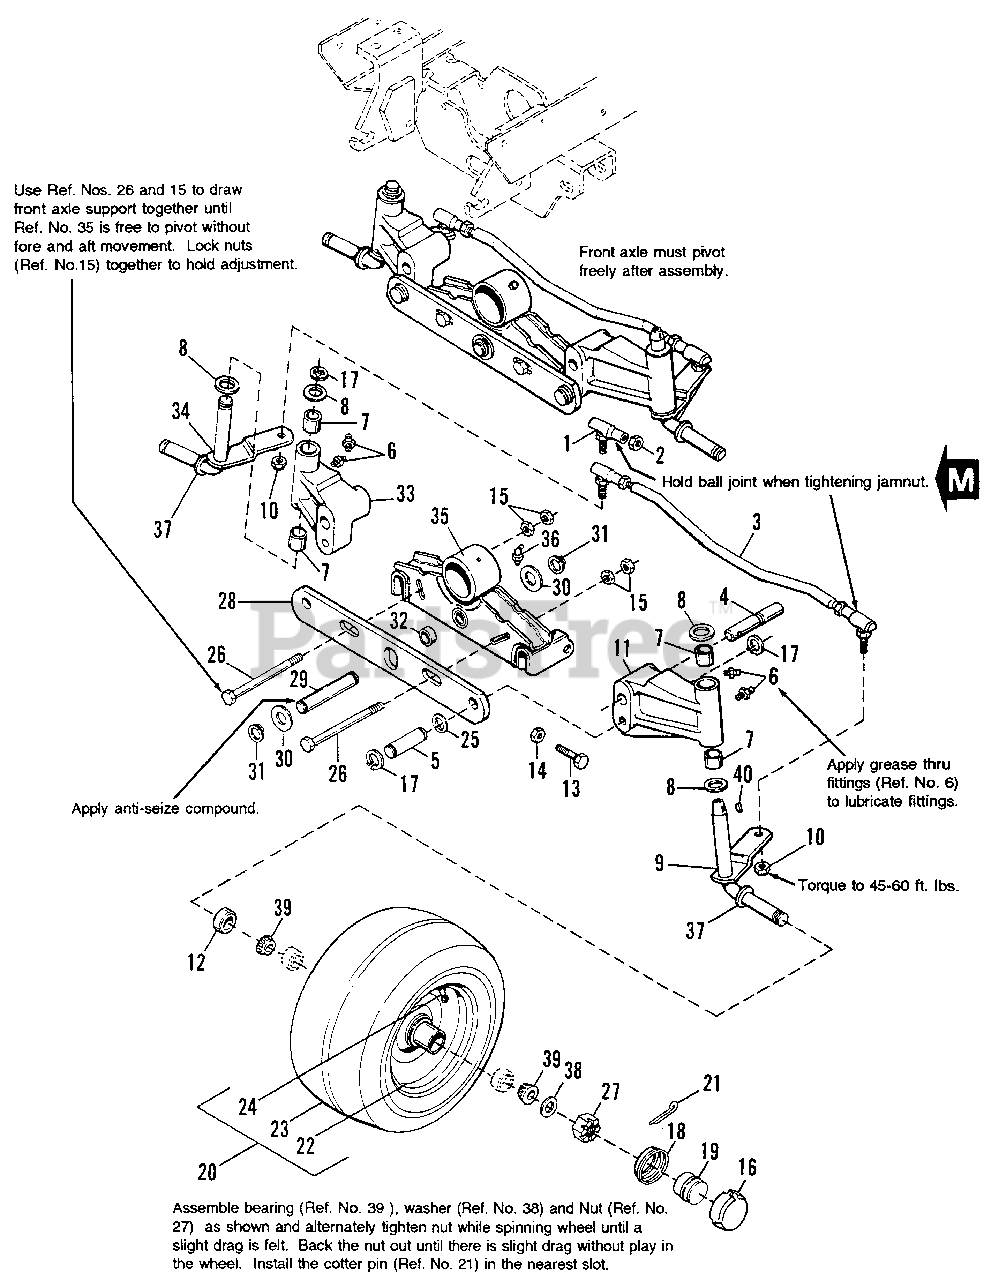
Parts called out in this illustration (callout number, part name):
1	BALL JOINT ASSY.
2	NUT, Hex, Jam, 1/2-20
3	TIE ROD ASSY. (Incl. Ref. No. 1 & 2)
4	PIN, Axle Pivot
5	PIN, Axle Pivot
6	FITTING, Lube, 1/4-28
7	BUSHING, Spindle
8	WASHER, 1-1/32 x 1-5/8 x 1/16
9	SPINDLE ASSY. L.H., (Includes Ref. No. 37)
10	NUT, Hex, Centerlock, 1/2-20
11	AXLE PIVOT ASSY., L.H. (Incl. Qty 2 of Ref. Nos. 6 & 7)
13	CAPSCREW, Hex Hd., 5/16-18 x 1-3/4, Gr. 5
14	NUT, Hex, Centerlock, 5/16-18
15	Nut, Hex, 3/8-16
16	CAP, Hub, Cover
17	RING, Retainer
18	RETAINER, Hub Cap
20	FRONT WHEEL & TIRE ASSY., 16 x 6.50-8 (Incl. Ref. Nos. 22. 23 & 24)
21	PIN, Cotter, 1/8 x 1 3/4
22	WHEEL ASSY., w/Bearings (Incl. Ref. No. 39)
23	TIRE, 16 x 6.50-8
24	VALVE STEM & CAP
25	WASHER, 1 1/32 x 1 3/4 x 7 Ga.
26	CAPSCREW, Hex Hd., 3/8-16 x 4
27	NUT, Hex, Slotted Hd., 3/4-16
30	WASHER, 3/4 I.D.
31	RING, Retaining, 3/4 I.D.
33	AXLE PIVOT ASSY., R.H. (Incl. Qty 2 of Ref. Nos. 6 & 7)
34	SPINDLE ASSY., R.H. (Includes Ref. No. 37)
35	HITCH SUPPORT ASSY.
36	FITTING, Lube, 45ø, 1/4", Drive Type
37	COLLAR, Seal, Spindle Assy.
39	BEARING, Cone
40	KEY, Hi-Pro, 1/4 x 3/4
